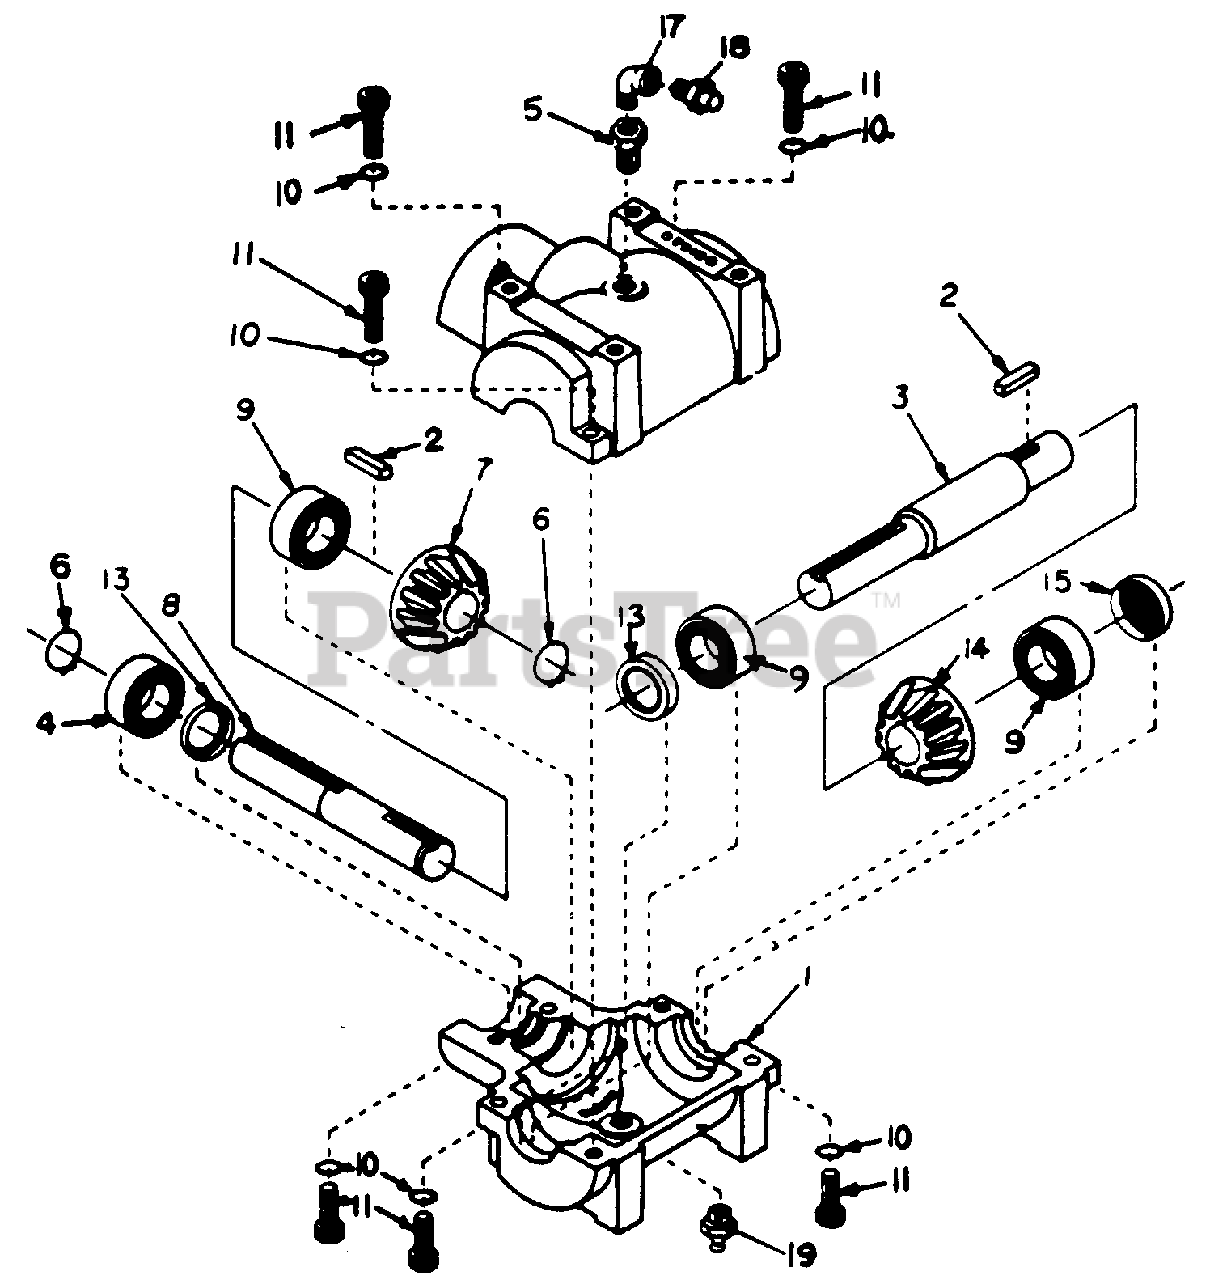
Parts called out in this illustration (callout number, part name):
2	Key, 3/16" x 3/16" x 1"
4	Ball Bearing
5	Pipe Bushing 1/4" x 1/8"
6	Retaining Ring
7	Output Shaft Gear
9	Ball Bearing
10	Lockwasher
11	Allenhead Capscrew
14	Input Shift Gear
15	Expansion Plug L
17	Street Elbow, 1/8" x 90ø
19	Grease, SHC-460
